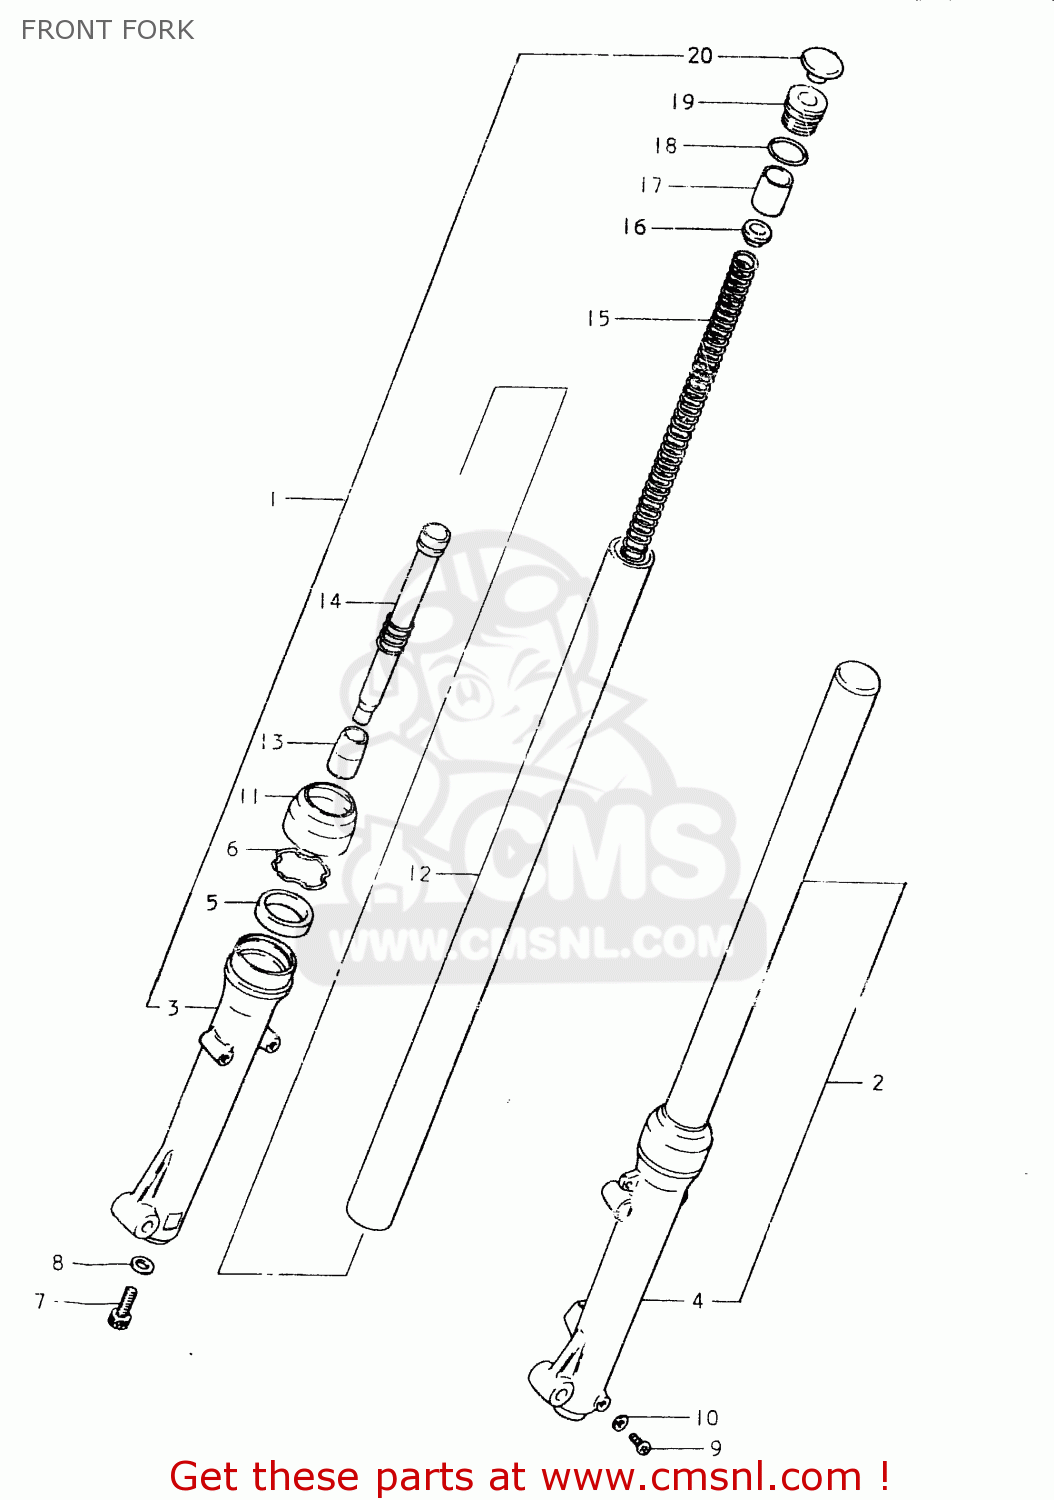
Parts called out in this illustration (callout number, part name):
1	DAMPER ASSEMBLY,RIGHT
2	DAMPER ASSEMBLY,LEFT
3	TUBE,OUTER,RIGHT
4	TUBE,OUTER,LEFT
5	OIL SEAL,FRONT FORK
6	7
7	BOLT,FORK CYLINDER(10X25)
8	GASKET (NAS)
9	SCREW
10	GASKET,DRAIN,PLUG (NAS)
11	SEAL,DUST
12	TUBE,FORK,INNER
13	PIECE,OIL LOCK
14	CYLINDER,FRONT FORK
15	SPRING
16	GUIDE,FRONT FORK SPRING C
17	SPACER,SPRING
18	O RING
19	CAP,FORK INNER TUBE
20	CAP,FRONT FORK
